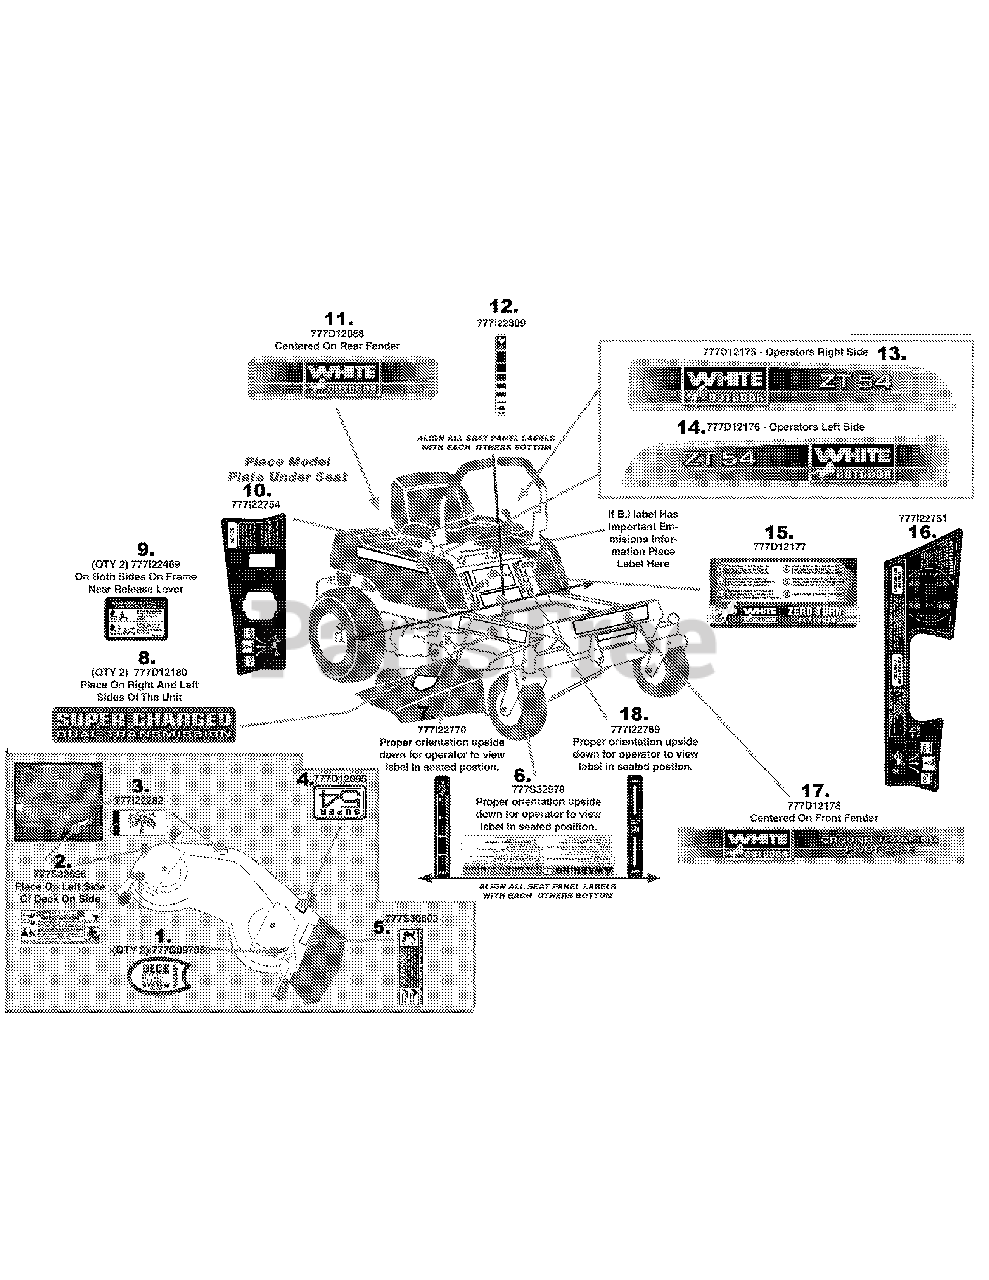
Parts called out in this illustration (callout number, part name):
1	LABEL:RIDER:WHITE
2	LABEL-RZT DECK WARNG STRAIGHT
3	LABEL-BELT ROUTE
4	LABEL-RIDER TOP DECK 54" CUT
5	LABEL-DANGER CHUTE
6	LABEL-COMMON WARNING
7	LABEL-HANDLE HEIGHT
8	LABEL-RZT SD SUPER CHARGED
9	LABEL-TRNMSN RELEASE
10	LABEL-RH CONTROL
11	LABEL-RIDER REAR FENDER WHITE
12	LABEL-THROTTLE
13	LABEL-RZT SD POD WHITE 54" RH
14	LABEL-RZT SD POD WHITE 54" LH
15	LABEL-RZT FEATURES
16	LABEL-LH CONTROL W/CHOKE
17	LABEL-RZT FRONT WHITE LOGO
18	LABEL-PARK BRAKE
